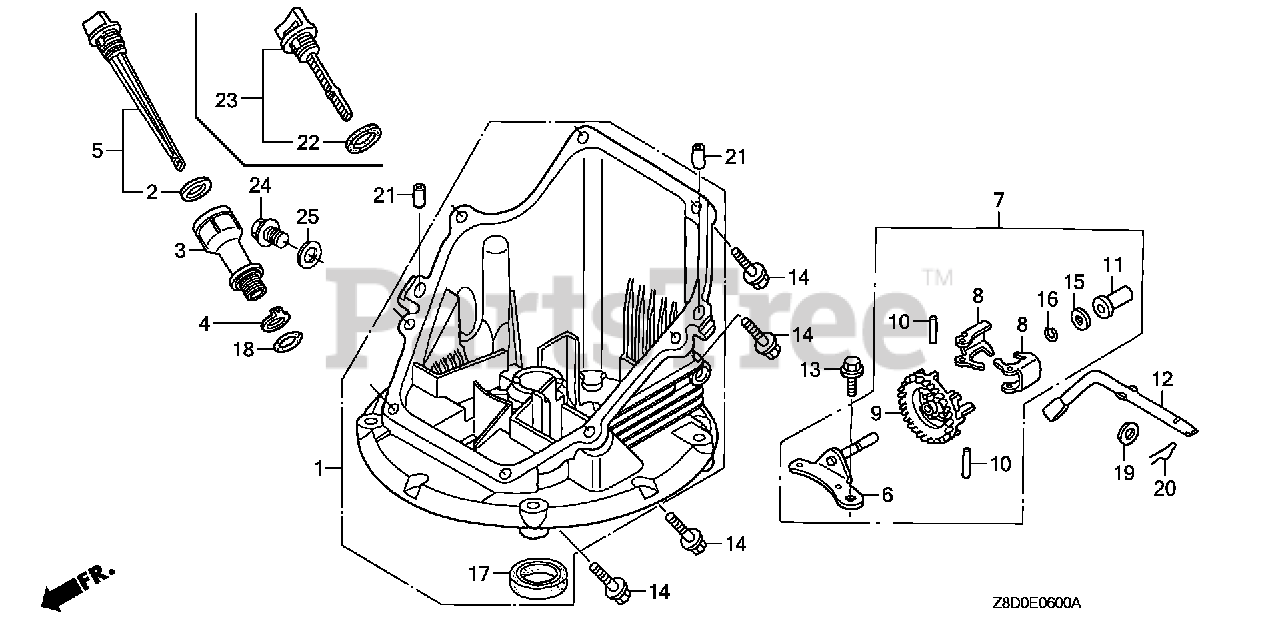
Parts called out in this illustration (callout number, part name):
1	PAN ASSY., OIL (SAE)
6	SHAFT, GOVERNOR HOLDER
7	GOVERNOR ASSY.
8	WEIGHT, GOVERNOR
9	HOLDER, GOVERNOR WEIGHT
10	PIN, GOVERNOR WEIGHT
11	SLIDER, GOVERNOR
12	SHAFT, GOVERNOR ARM
13	BOLT, FLANGE (6X14) (CT200)
14	BOLT, FLANGE (6X25) (CT200)
15	WASHER, THRUST (6MM)
16	CLIP, GOVERNOR HOLDER
17	OIL SEAL (28X41.25X6) (NOK)
19	WASHER, PLAIN (6MM)
20	PIN, LOCK (8MM)
21	PIN, DOWEL (8X20)
22	GASKET, OIL FILLER CAP
23	GAUGE ASSY., OIL LEVEL
24	BOLT, DRAIN PLUG (12X15)
25	WASHER, DRAIN PLUG (12MM)
